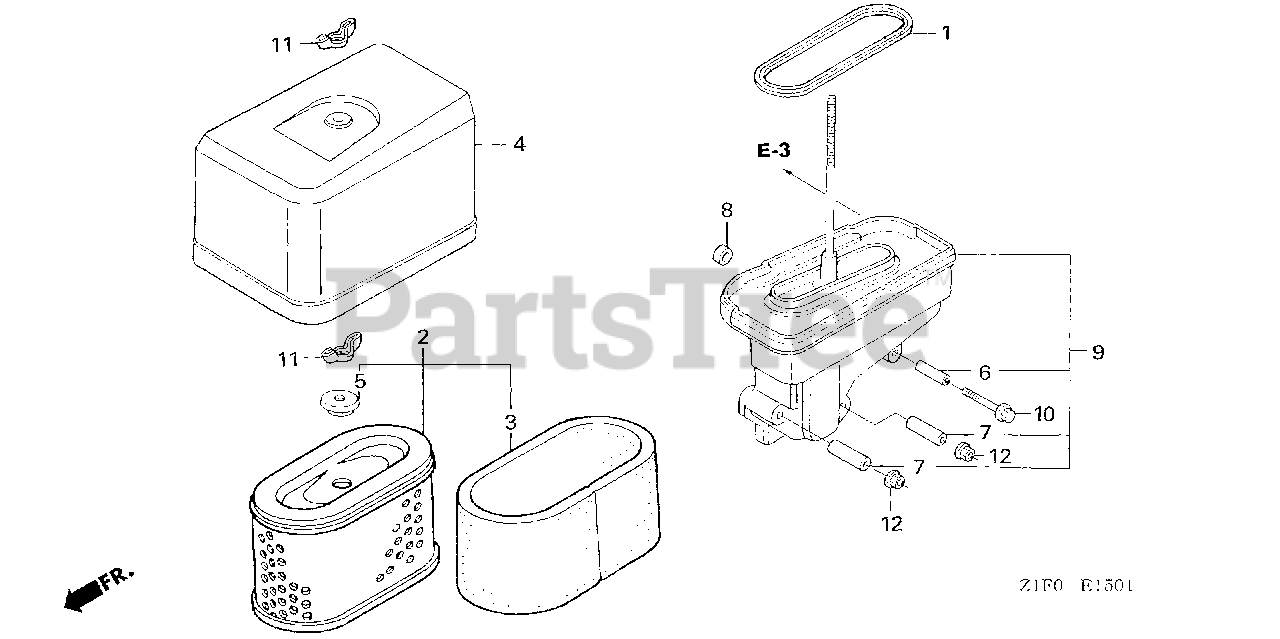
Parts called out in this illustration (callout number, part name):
1	GASKET, ELBOW
2	ELEMENT, AIR CLEANER (METAL BASE)
3	FILTER (OUTER)
4	COVER, AIR CLEANER (DUAL)
5	GROMMET, AIR CLEANER
6	COLLAR, AIR CLEANER Use up to Engine SN 1786084.
7	COLLAR, AIR CLEANER
8	SPACER, AIR CLEANER ELBOW
9	ELBOW, AIR CLEANER
10	BOLT, FLANGE (6X35)
11	WINGNUT, TOOL BOX SETTING
12	NUT, FLANGE (6MM)
